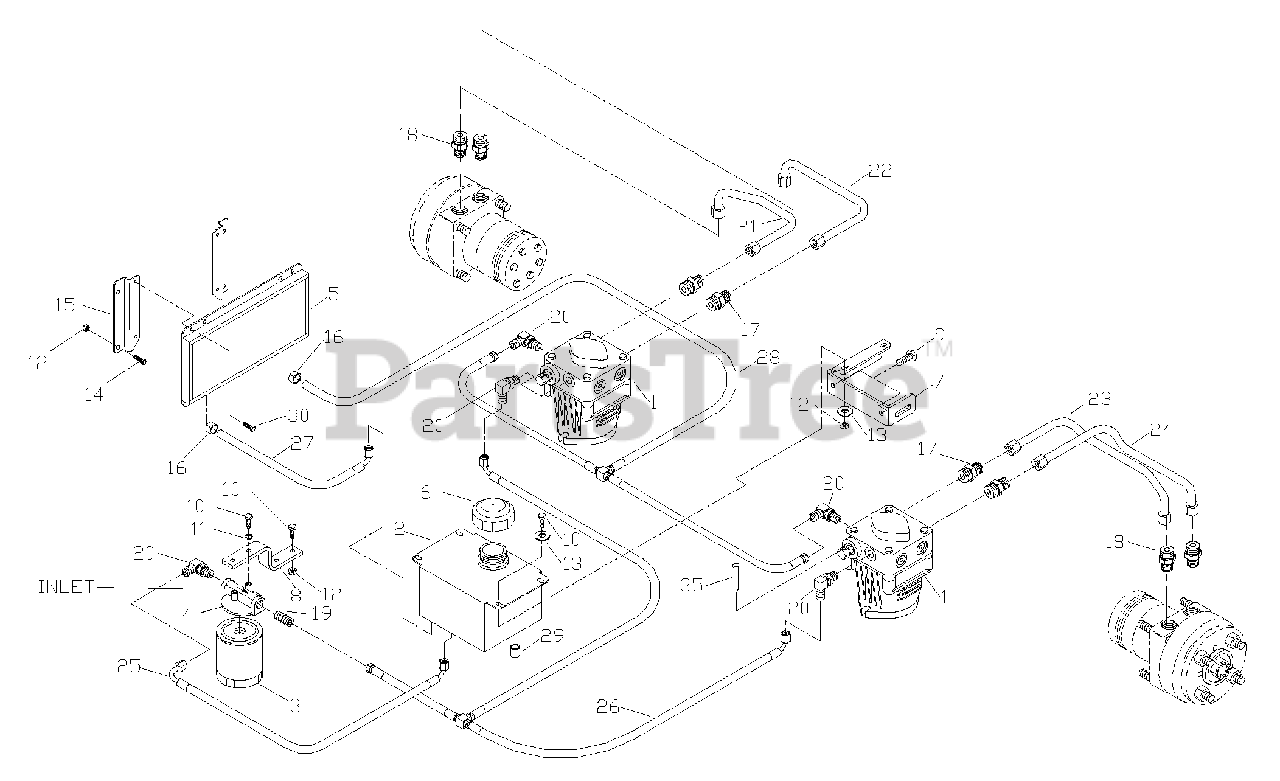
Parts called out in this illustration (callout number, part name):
1	PUMP
3	FILTER
4	FILTER HEAD
7	TANK MOUNT LT
7	TANK MOUNT RT
8	FILTER BRACKET
9	HCS 5/16 X 3/4
10	HCS 1/4C X 3/4
11	1/4 LOCK WASHER
12	1/4 LOCK NUT
13	1/4 FLAT WASHER
14	HCS 1/4C X 2.0
15	COOLER BRACKET
16	HOSE CLAMP
18	STR FITTING
26	"T" ASM (SUCTION)
28	"T" ASM (RETURN)
30	HCS 1/4 SELF TAP
